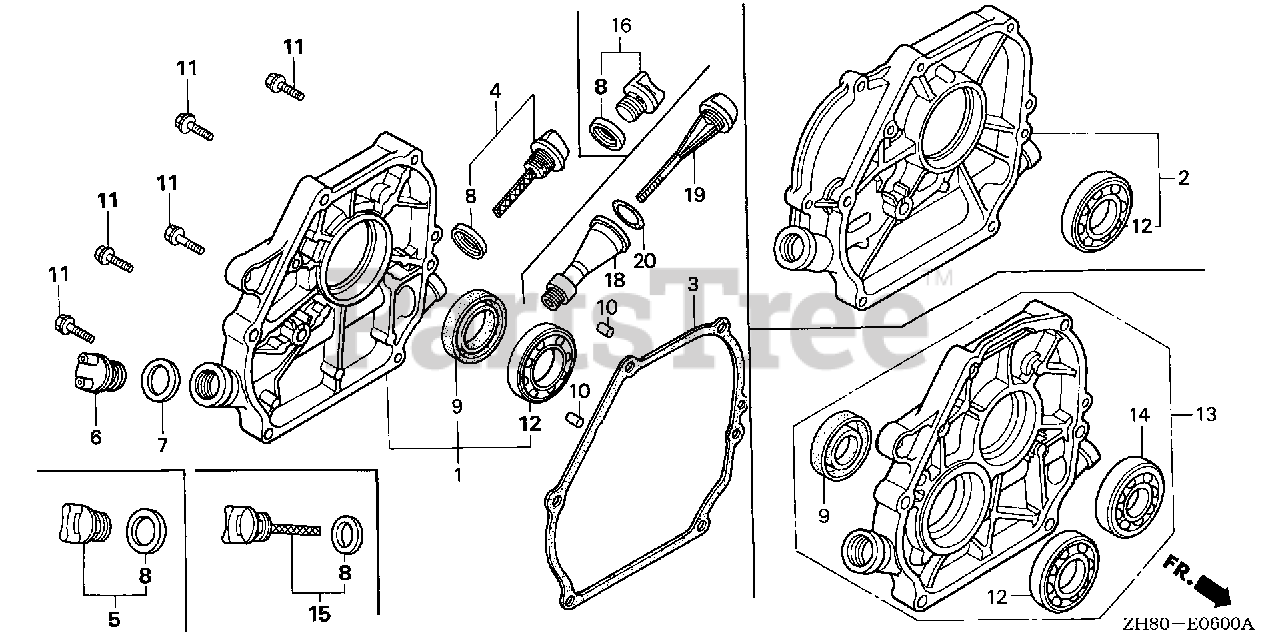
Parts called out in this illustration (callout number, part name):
1	COVER ASSY., CRANKCASE
3	GASKET, CASE COVER
3	GASKET, CASE COVER (NON-ASBESTOS)
4	CAP ASSY., OIL FILLER (GRAY)
5	CAP ASSY., OIL FILLER
7	GASKET, OIL FILLER CAP
8	GASKET, OIL FILLER CAP
9	OIL SEAL (25X41X6)
10	PIN, DOWEL (8X14)
11	BOLT, FLANGE (8X32)
12	BEARING, RADIAL BALL (6205)
